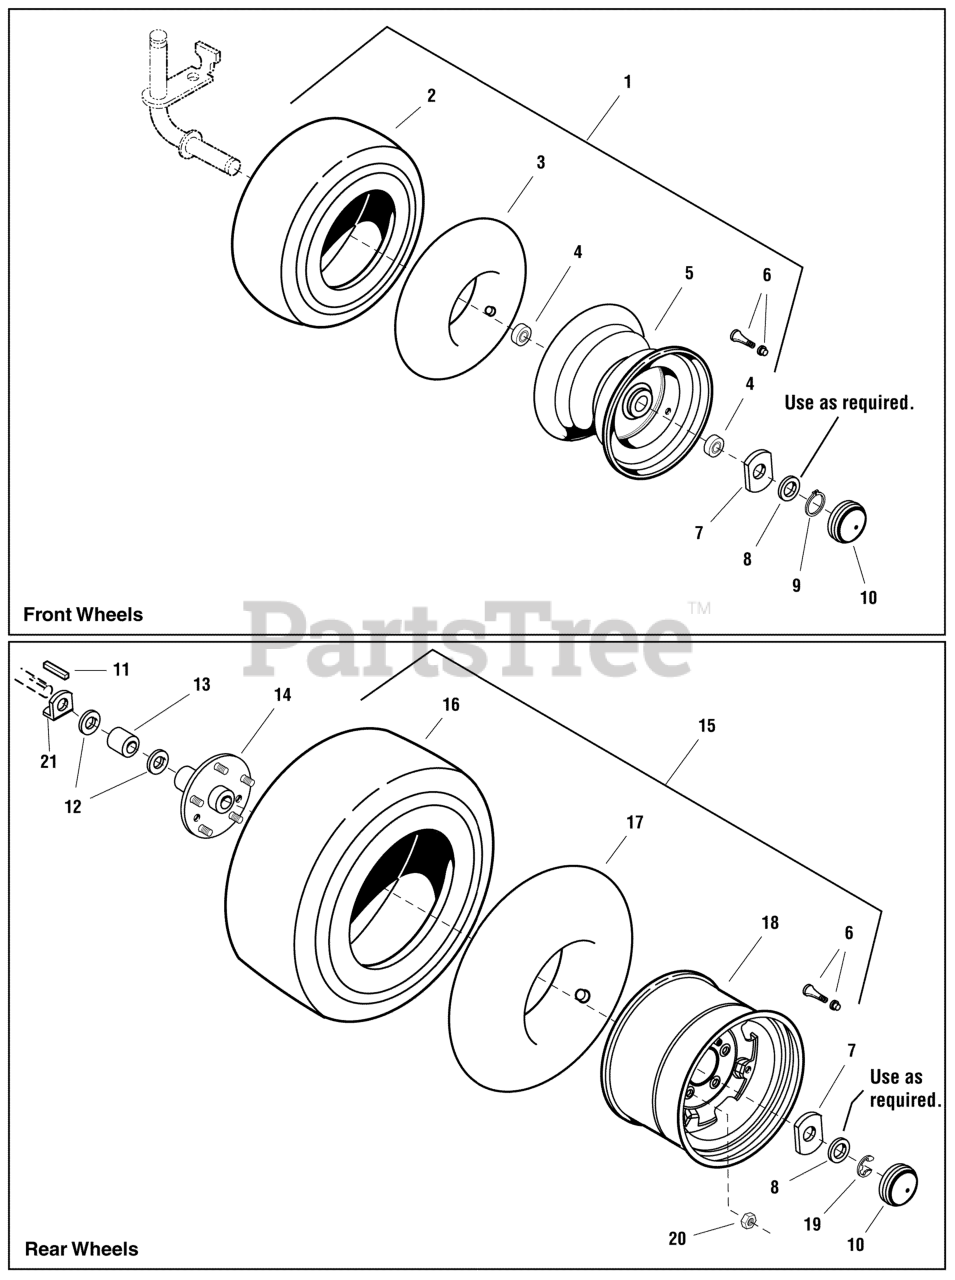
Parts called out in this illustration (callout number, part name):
1	WHEEL & TIRE ASSEMBLY, Front
2	TIRE, 16 x 6-1/2 - 8 Super Turf, Front
3	TUBE, Tire 16 x 6-1/2 - 8, Front
4	BEARING, Ball
5	WHEEL, 5 3/8 x 7-15/16, Front
6	VALVE STEM & CAP ASSEMBLY
7	WASHER, Special, 1 x 2-1/2
8	WASHER
9	RING, Retainer
10	CAP, Hub Grey, 2-23/64
11	KEY, HI PRO, 1/4 x 2
13	SPACER, 1-1/16 x 1-1/2 x 1-23/32, Black
14	PLATE & HUB ASSEMBLY, Rear Wheel w/Studs
15	WHEEL & TIRE ASSEMBLY, Rear 23"
16	TIRE, 23 x 10-1/2 - 12 Super Turf, Rear
17	TUBE, Tire 23 x 10-1/2 - 12, Rear
18	WHEEL, 7 x 12, Rear
19	RING, Shaft
20	NUT, Hex 7/16-20, For Wheel Bolt
21	BRACKET, Washer Axle
